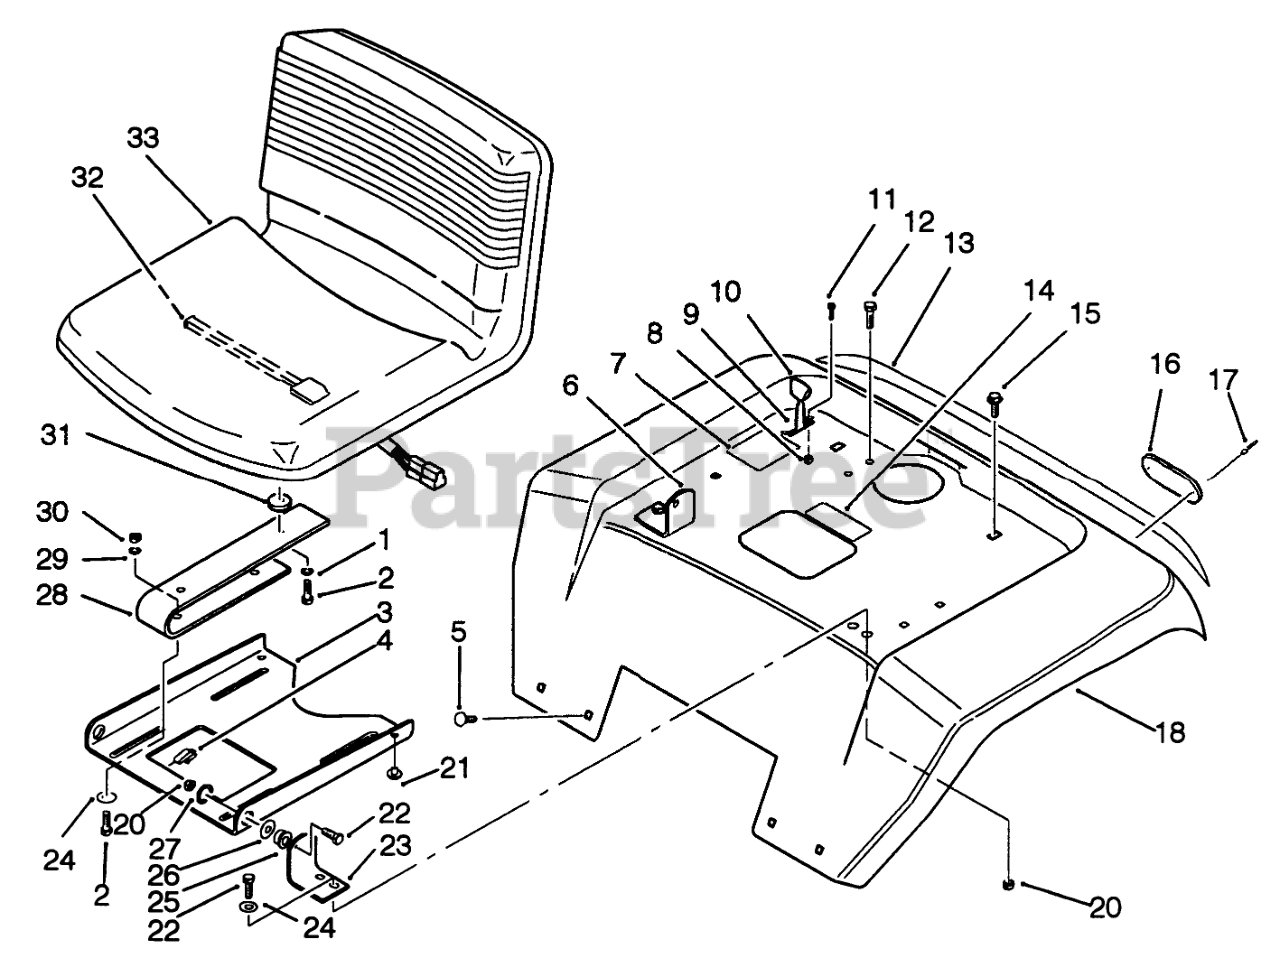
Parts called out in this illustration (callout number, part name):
1	Lockwasher
2	SCREW-HH
3	Plate-SeatPivot
4	J-CLIP
5	SCREW-CARR
6	Bracket-Pivot RH
7	DECAL-PUSH
8	Nut
9	CONTROL-PUSH VALVE
10	KNOB-THROTTLE
11	SCREW
12	Screw-Hex Hd.
13	DECAL-FENDER
14	DECAL-DANGER
15	Screw
16	Reflector
17	Poprivet
18	WLDMT-FENDER R
21	BUMPER-RUBBER
22	SCREW-HH
23	BRKT-PIVOT L.H. B
24	WASHER-PLAIN
25	BUSHING
26	WASHER-SPECIAL
27	WASHER-SPRING
28	Seat Spring
29	WASHER-PLAIN
30	NUT-LOCK, NI
31	SPACER-NYLON
32	SWITCH-SEAT
33	SEAT V-510
